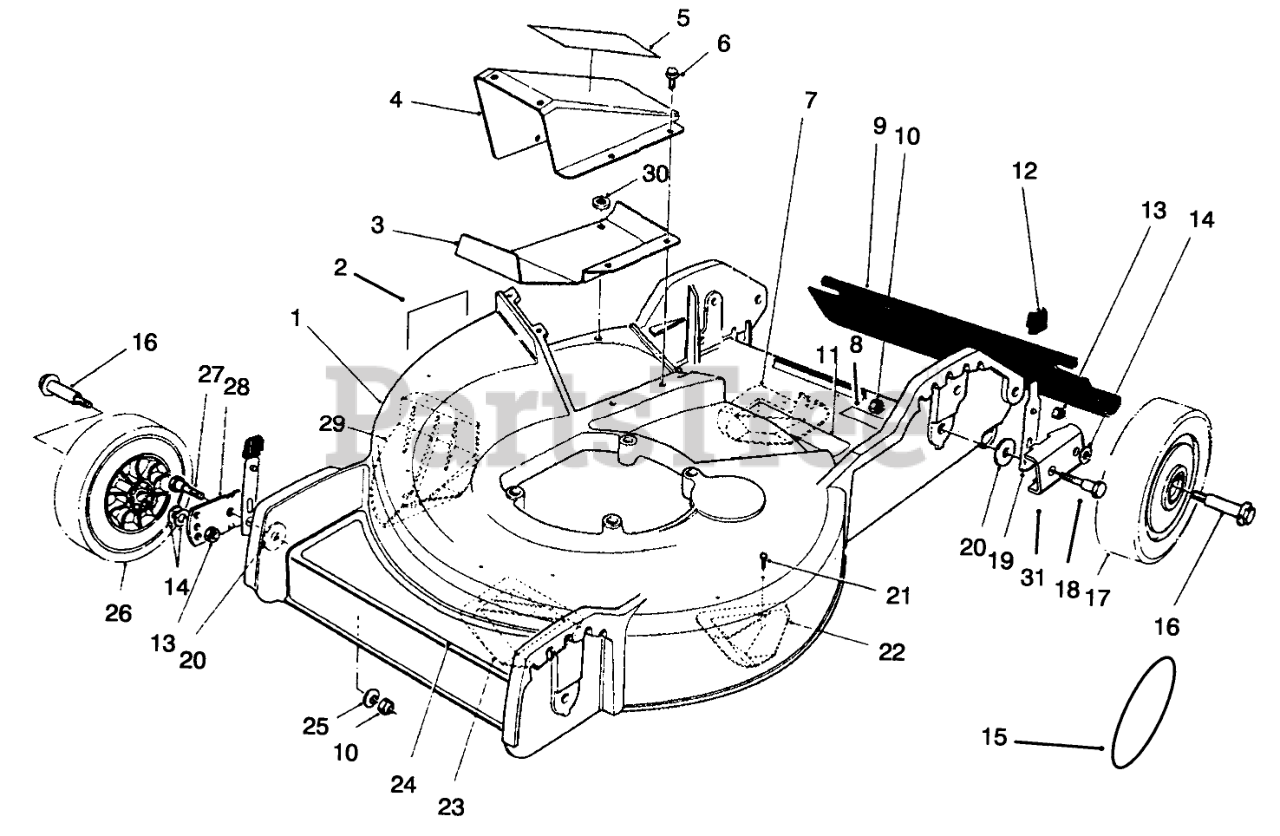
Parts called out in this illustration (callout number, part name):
1	Housing-46cm (Incl. Ref. #2, 7, 8,11, 21, 22, 23, & 23)
2	DECAL - DIN/DANGER
3	DISCHARGE KICKER
4	Cover-Discharge(Incl. Ref. #5)
5	DECAL - DANGER
6	SCREW
7	KICKER
8	DECAL FRENCH REGUL.
9	SHIELD - TRAILING
10	NUT-LOCK, NI
11	DECAL - DANGER
12	KNOB-ARM
13	NUT-HEX
14	WASHER
15	COVER-WHEEL
16	BOLT-WHEEL
17	WHL & TIRE ASSEMBLY
18	PIVOT SCREW
19	SPRING ARM ASM
20	PIVOT WASHER
21	SCREW-PPH
22	KICKER
23	KICKER
24	DECAL - DECK
25	WASHER-BELLEVILLE
26	7 " WHEEL/TIRE ASM
27	5/16-18 PIVOT SCREW
28	PIVOT ARM ASSY
29	KICKER
30	WASHER-FLAT
31	PIVOT ARM ASM
